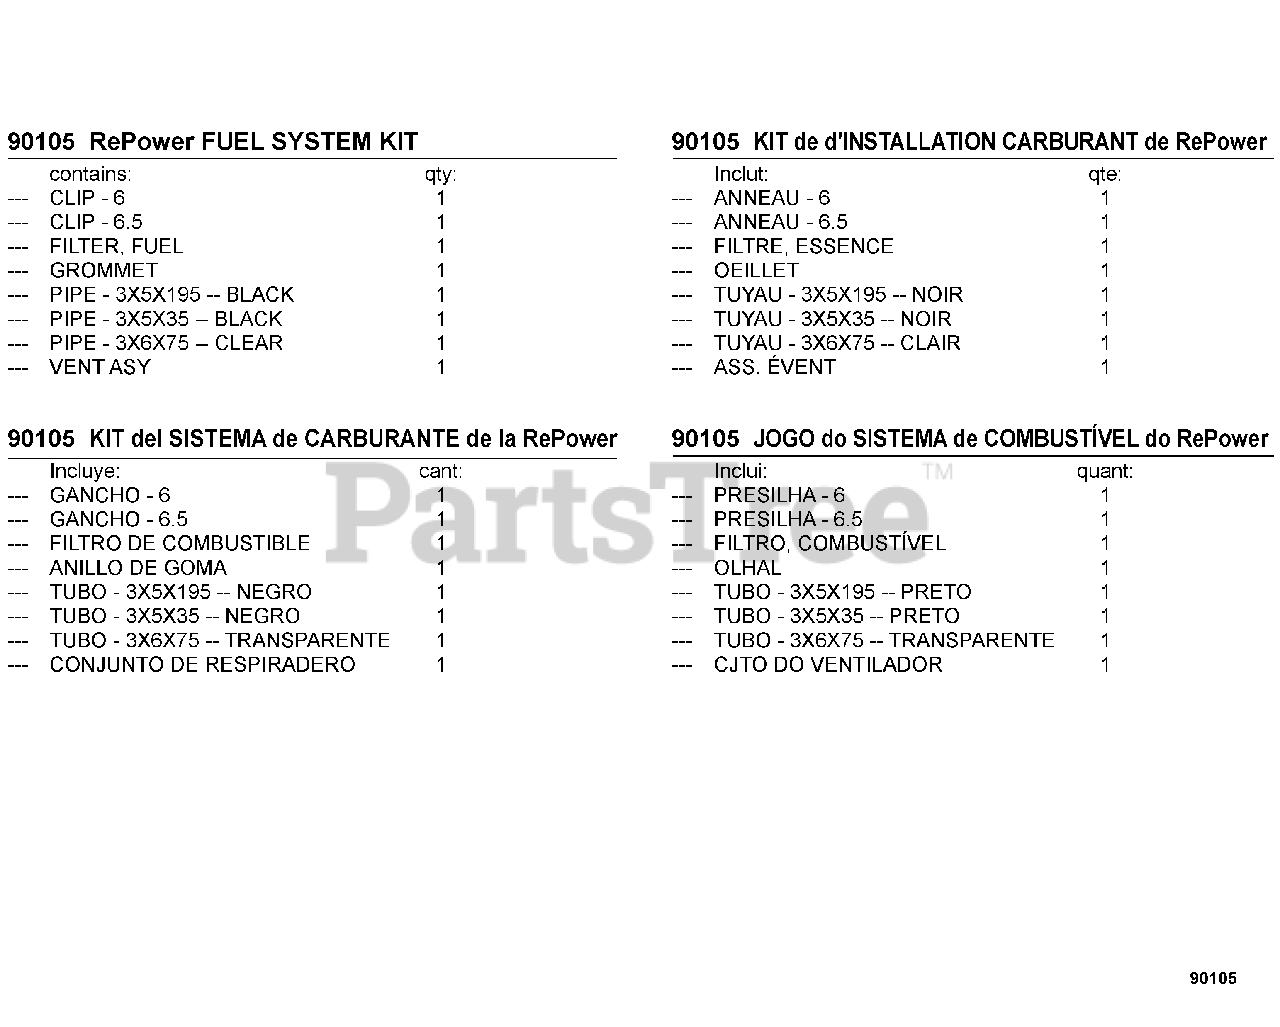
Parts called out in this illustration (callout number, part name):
1	GASKET KIT
2	GASKET, CRANKCASE
3	GASKET, CYLINDER
4	HEAT SHIELD, INTAKE
5	GASKET, INTAKE
6	HEAT SHIELD, EXHAUST
7	GASKET, EXHAUST
8	TUNE-UP KIT - REPOWER
9	PRE-FILTER, FOAM
10	FILTER, AIR - DOUBLE LAYER
11	FILTER, FUEL
12	SPARK PLUG - BPMR8Y
13	FUEL SYSTEM KIT
14	VENT ASSY
15	CLIP Ø6.5 MM
16	PIPE, FUEL 3×6×35 BLACK
17	PIPE, FUEL 3×5×195 BLACK
18	PIPE, FUEL 3×6×75 CLEAR
19	GROMMET, FUEL
20	CLIP Ø6
21	FILTER, FUEL 125-528
22	FUEL SYSTEM KIT
23	VENT ASSY
24	CLIP Ø6.5 MM
25	PIPE, FUEL 3×6×35 BLACK
26	PIPE, FUEL - 3×5×67 - BLACK
27	PIPE, FUEL 3×6×75 CLEAR
28	GROMMET, FUEL
29	CONNECTOR, PIPE Ø5ר3.5
30	CLIP Ø6
31	PIPE, FUEL - 3×5×125 - BLACK
32	FILTER, FUEL 125-528
33	GASKET, FUEL CAP
34	CAP/VENT KIT - REPOWER
35	CAP, FUEL
36	VENT ASSY
37	GASKET, FUEL CAP
38	BULK PIPE - 3×5 MM BLACK (4 PIECES×2 M)
39	BULK PIPE - 3×6 MM CLEAR (4 PIECES×2 M)
40	BULK PIPE - 3×6 MM BLACK (4 PIECES×2 M)
41	BULK STARTER ROPE - Ø 3.0 MM×61 M
